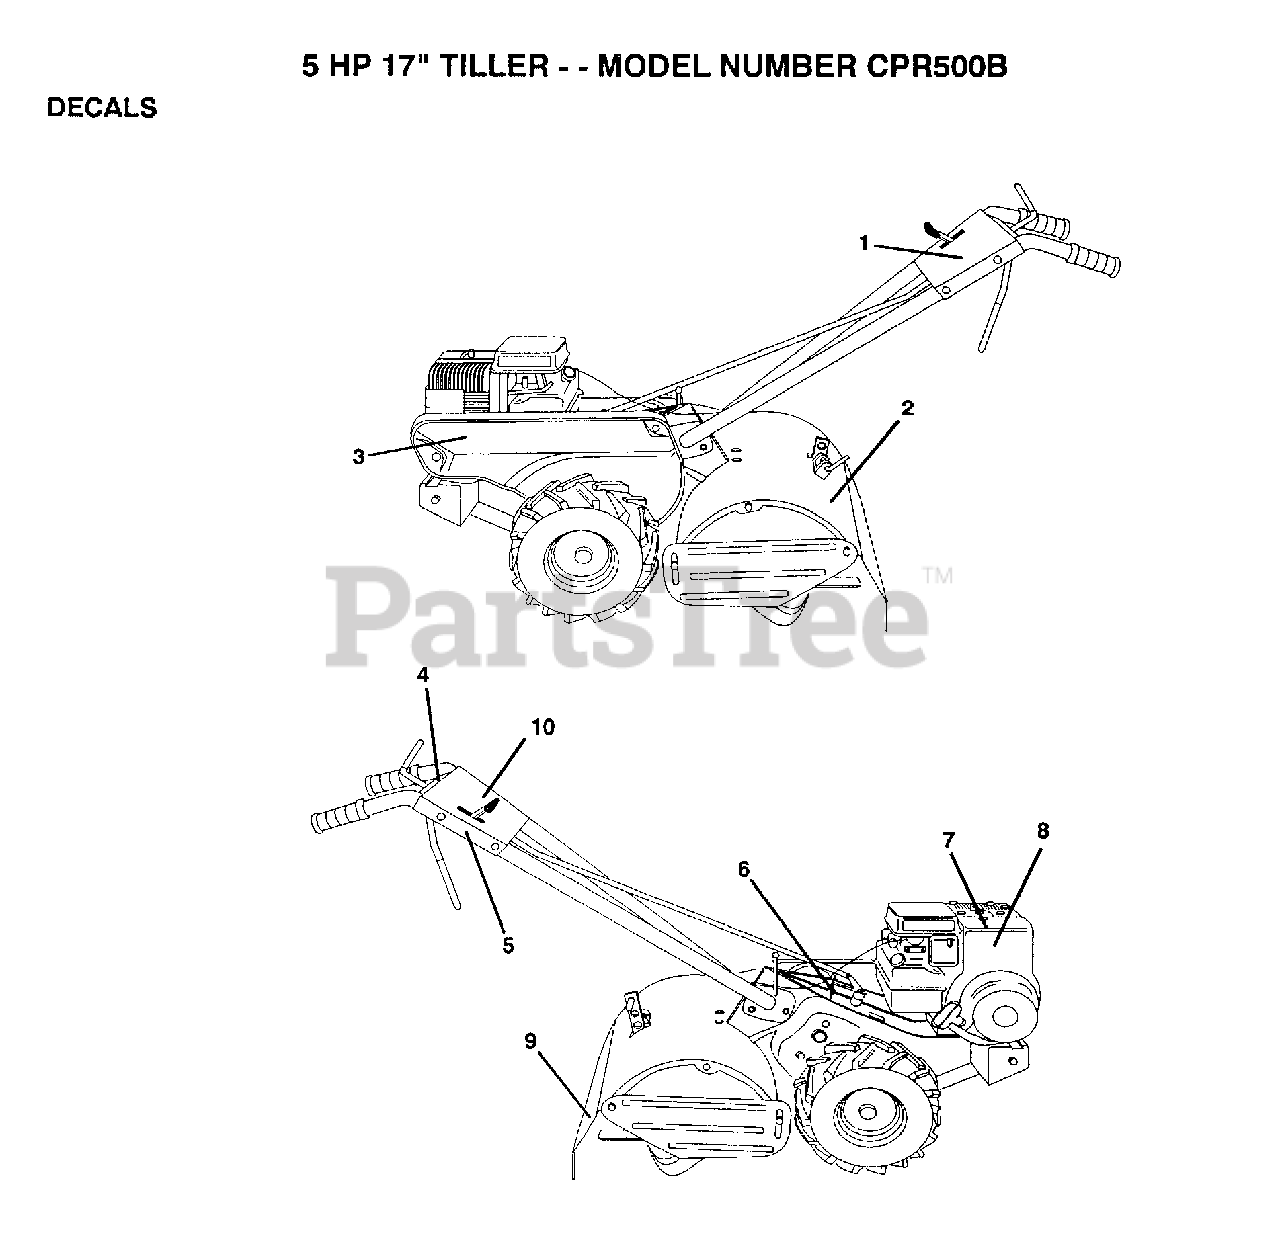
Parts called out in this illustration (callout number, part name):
1	DECAL, LOGO
2	DECAL, LOGO
3	DECAL, LOGO
5	DECAL TI
6	DECAL CRT
9	DECAL TI
10	DECAL, PANEL CONTROL
